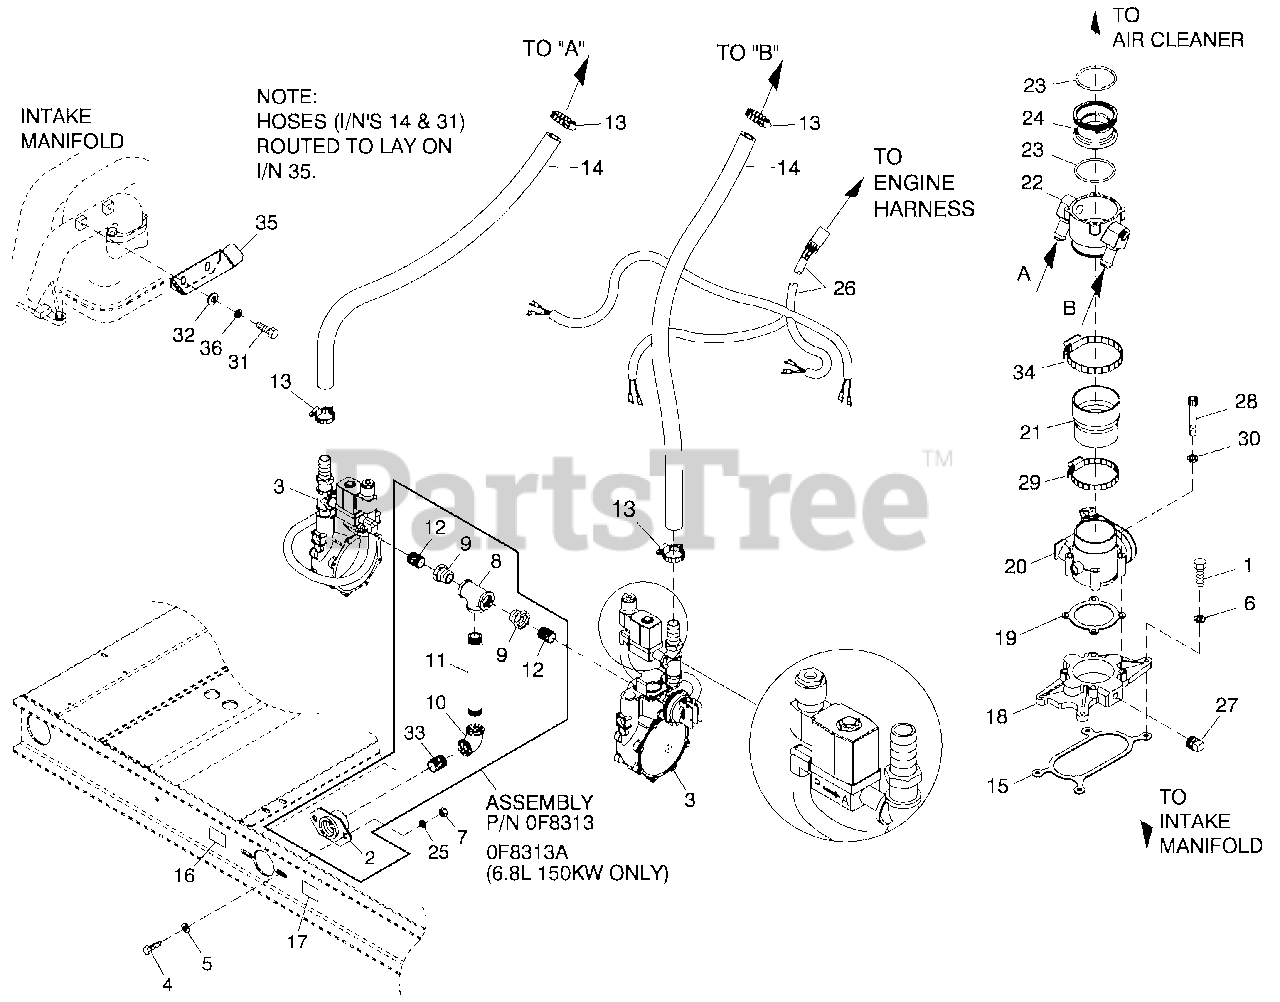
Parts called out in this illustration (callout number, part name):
1	SCREW HHC 5/16-18 X 1-1/4 G5
2	SUPPORT NAT GAS SOLENOID
3	REG ASSY 6.8L 130 KW DUAL LP QT
4	SCREW HHC M12-1.75 X 20 G8.8
5	WASHER FLAT 1/2 ZINC
6	WASHER LOCK M8-5/16
7	NUT HEX M12-1.75 G8 YEL CHR
8	PIPE TEE 1-1/4 NPT
9	BSHG RDCRHEX1-1/4-3/4
10	ELBOW 90D1-1/4 NPT
11	NIPPLE PIPE 1-1/4 NPT X 3 (100KW & 130 KW)
12	NIPPLE CLOSE 3/4X1.375
13	CLAMP HOSE #10 .56-1.06
14	HOSE 3/4 ID SAE-30R2 (45" LG)
15	GASKET ADAPTER THROT BODY
16	DECAL INLET PRESSURE
17	DECAL FUEL INLET LPG
18	ASSY,ADAPTER,THROTTLE BODY
19	GASKET GOVERNOR ACTUATOR
20	ACTUATOR BOSCH 60 GOVERNOR
21	REDUCER 3.0" TO 2.75" TURBO
22	MIXER 40/60MM ACTUATOR ASSY
23	O-RING 2-3/4X3/32X2-15/16
24	VENTURI THROTTLE 42MM (6.8L 100 KW)
25	WASHER LOCK 1/2
26	HARNESS, FUEL JUMPER DUAL REG
27	PLUG STD PIPE 1/4 STEEL SQ HD
28	SCREW SHC M6-1.0 X 50 C8.8
29	CLAMP HOSE #44 2.31-3.25
30	WASHER LOCK M6-1/4
31	SCREW HHC M6-1.0X 20 G8.8
32	WASHER FLAT M6
33	NIPPLE CLOSE 1.25 NPT X 1.625
34	CLAMP HOSE #52 2.81-3.75
35	BRACKET, HOSE RISER
36	WASHER LOCK M6-1/4
